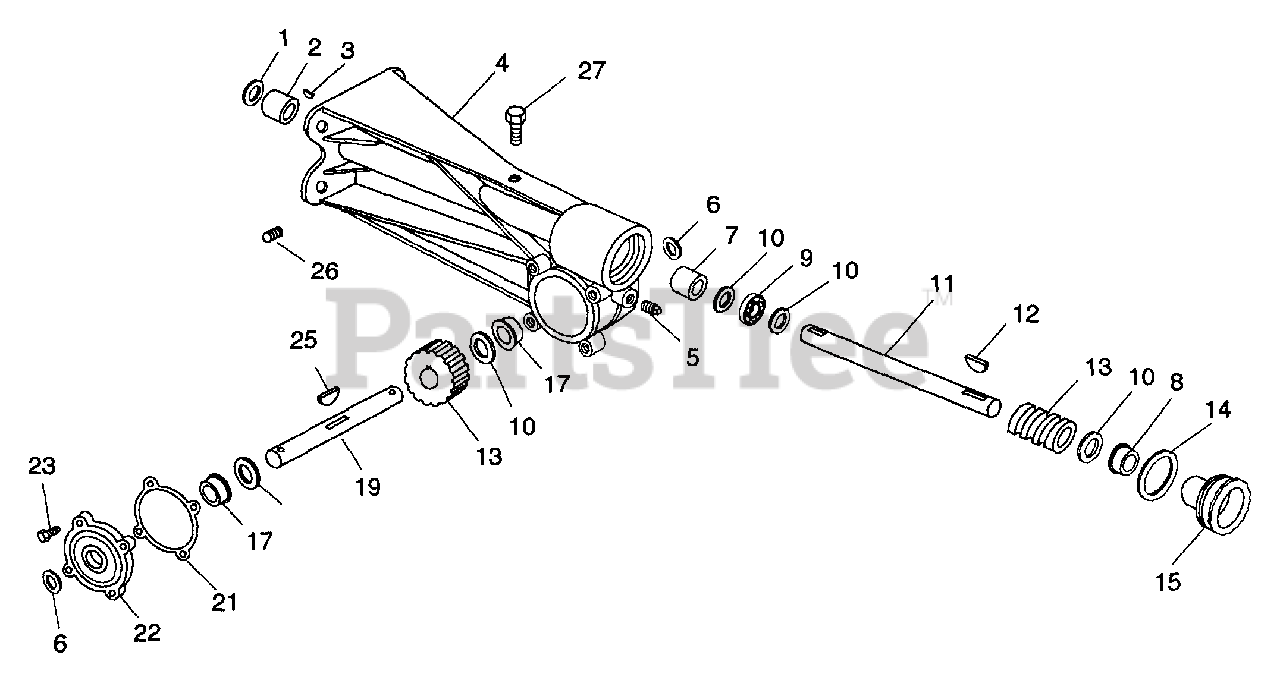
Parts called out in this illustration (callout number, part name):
1	SEAL .750X1.000X.125
2	BSHG-SLV .750X1.000X1.000
3	KEY-WDRF .188X.875X.375 SAE11
4	GEARCASE - ALUMINUM
5	PIPE PLUG
6	SEAL .750X1.980X.375
7	BSHG-SLV .750X1.000X.750
8	BSHG-FLG .750X1.000X.750X1.132
9	BRG-N THRST .754X1.24X.078
10	WSHR-HDND-THRST .755X1.40X.062
11	WORM SHAFT
12	KEY-FTHR .188X1.38X.188
13	WORM AND WORM GEAR SERVICE
14	GASKET
15	ADJUSTMENT PLUG
17	NUT-JAM .50-20 LH THD PL
19	TINE SHAFT
21	GASKET
22	COVER
23	SCR-TAP .312-18X1.0 HWH PL TR
25	KEY-WDRF .188X.625X.25 SAE 61
26	BREATHER
27	SCR-TAP .375-16X .50 HWH PL TR
28	ARIENS 16 OZ.BOTTLE OF L2 LUBE
